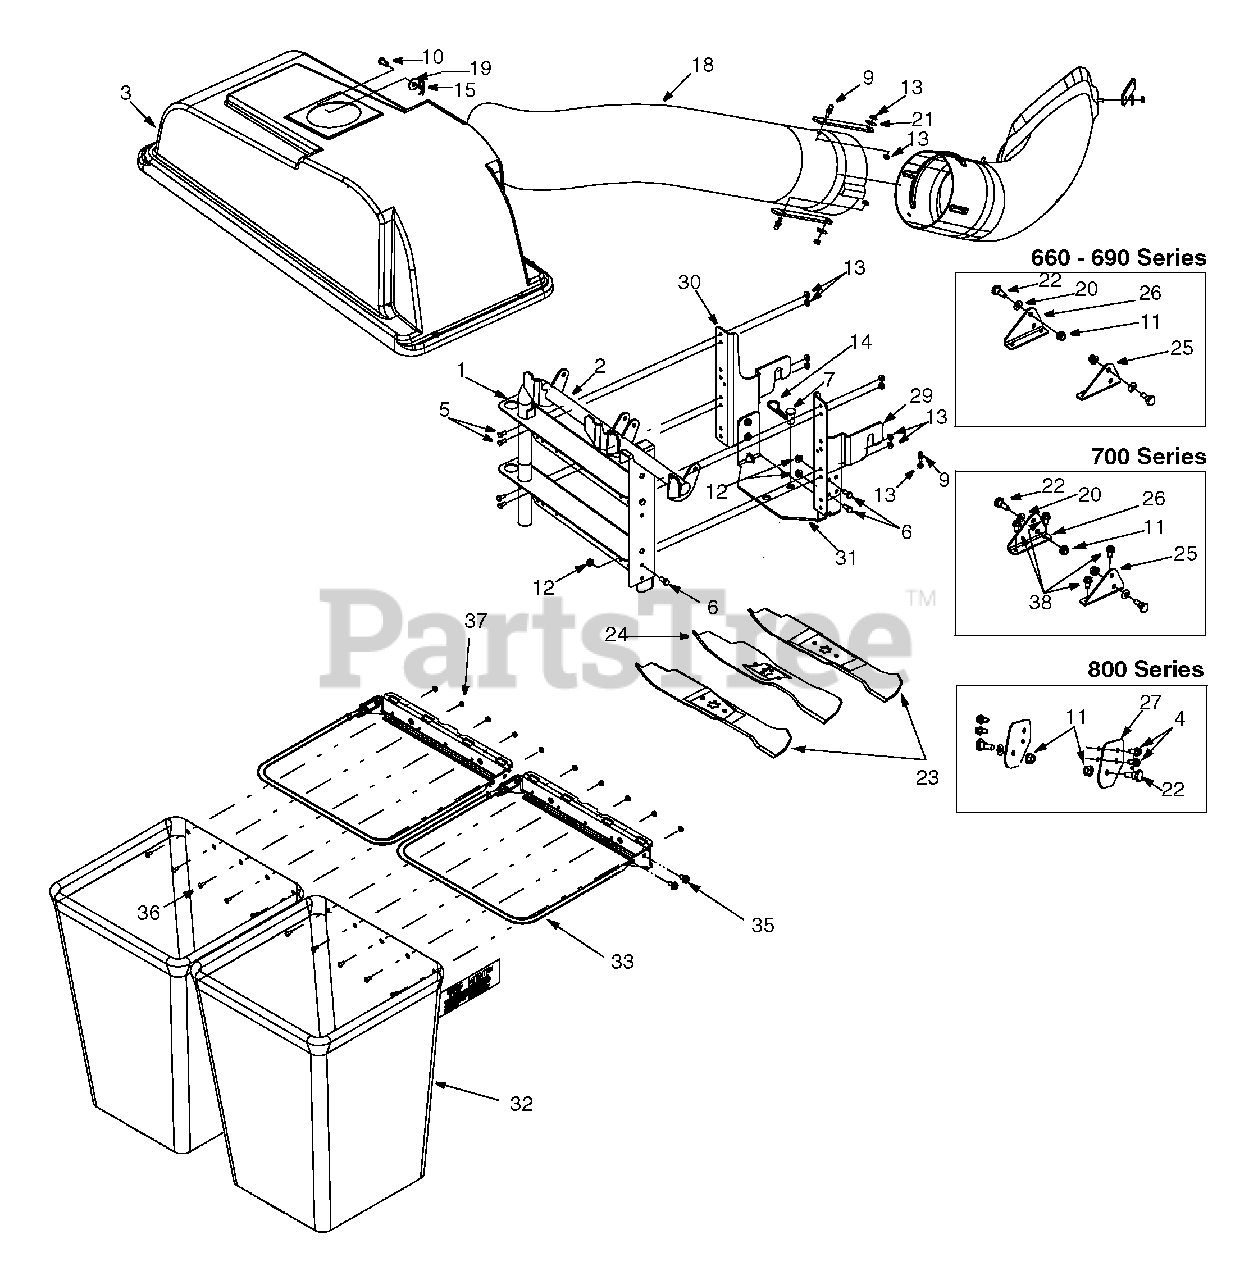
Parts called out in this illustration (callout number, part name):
3	Grass catcher Cover Assembly
4	Self-tapping Screw 3/8-16 x 0.75"
5	Hex Screw 1/4-20 x0.620
6	Hex Screw 5/16-18 x 0.75"
7	Clevis Pin
9	Grass catcher Pin
10	Clevis Pin
11	Lock Nut 7/16-20
12	Lock Nut 5/16-18
13	Flange Lock Nut 1/4-20
14	Hairpin Clip
15	Click Pin
16	Chute Strap
17	Discharge Chute 46"
18	Catcher Tube
19	Bell Washer
20	Bell Washer
21	Flat Washer
22	Shoulder Screw
23	Blade 16.28" Lg.
24	Blade 14.88" Lg.
25	Supt. Bracket
26	Supt. Bracket
32	Catcher Bag
34	Hex Sems Nut, #10-24
35	Self-tapping Screw, 5/16-18 x .625
36	Machine Screw, #10-24 x .5
38	AB Screw 5/16-12
